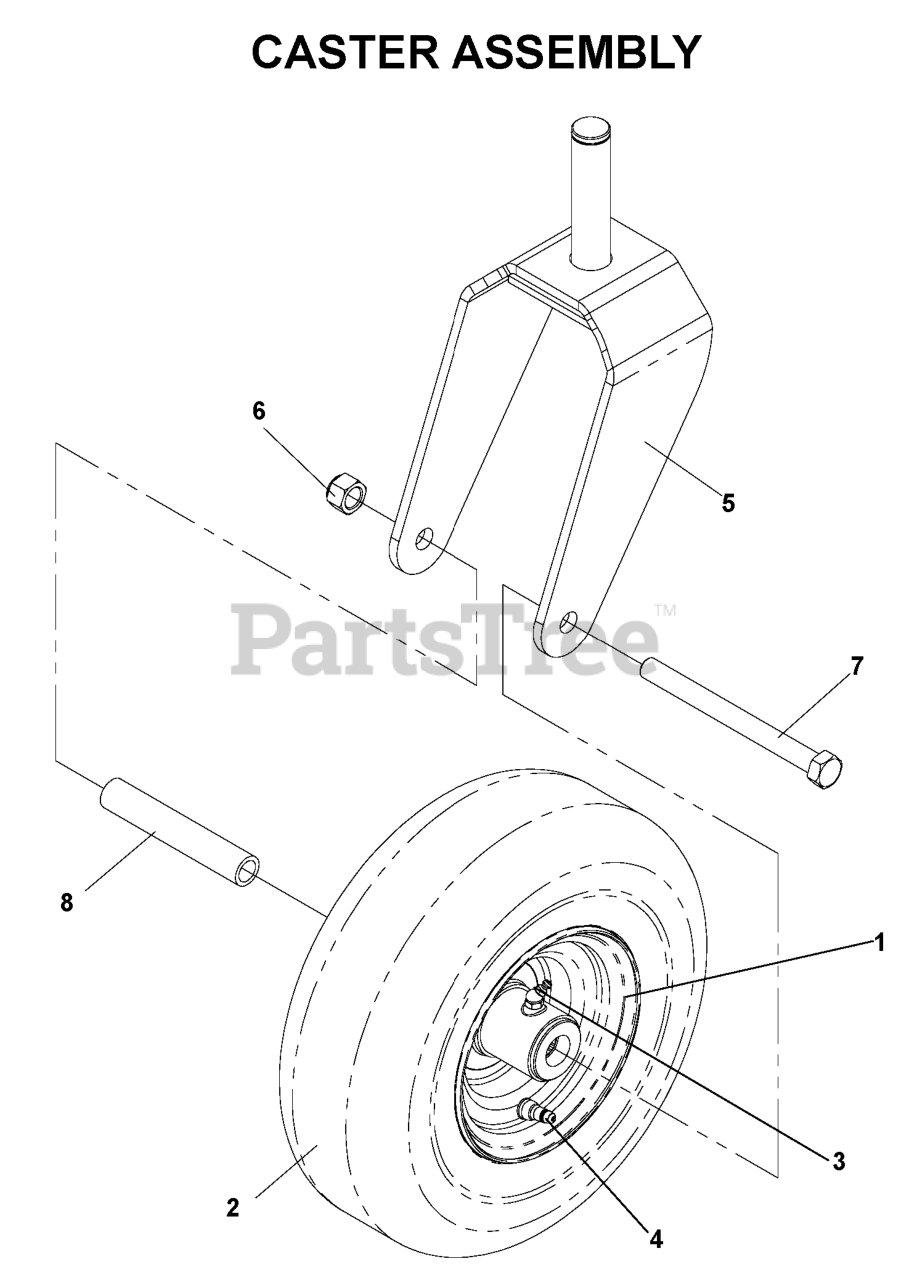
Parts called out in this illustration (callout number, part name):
2	TIRE - CASTER
3	ZERK
4	VALVE STEM TR-412
5	CASTER WLDT
6	NUT 1/2-13 HEX NYLOC ZD
7	HCS 1/2C X 5 1/2
539106993	TIRE/WHEEL.CASTER
